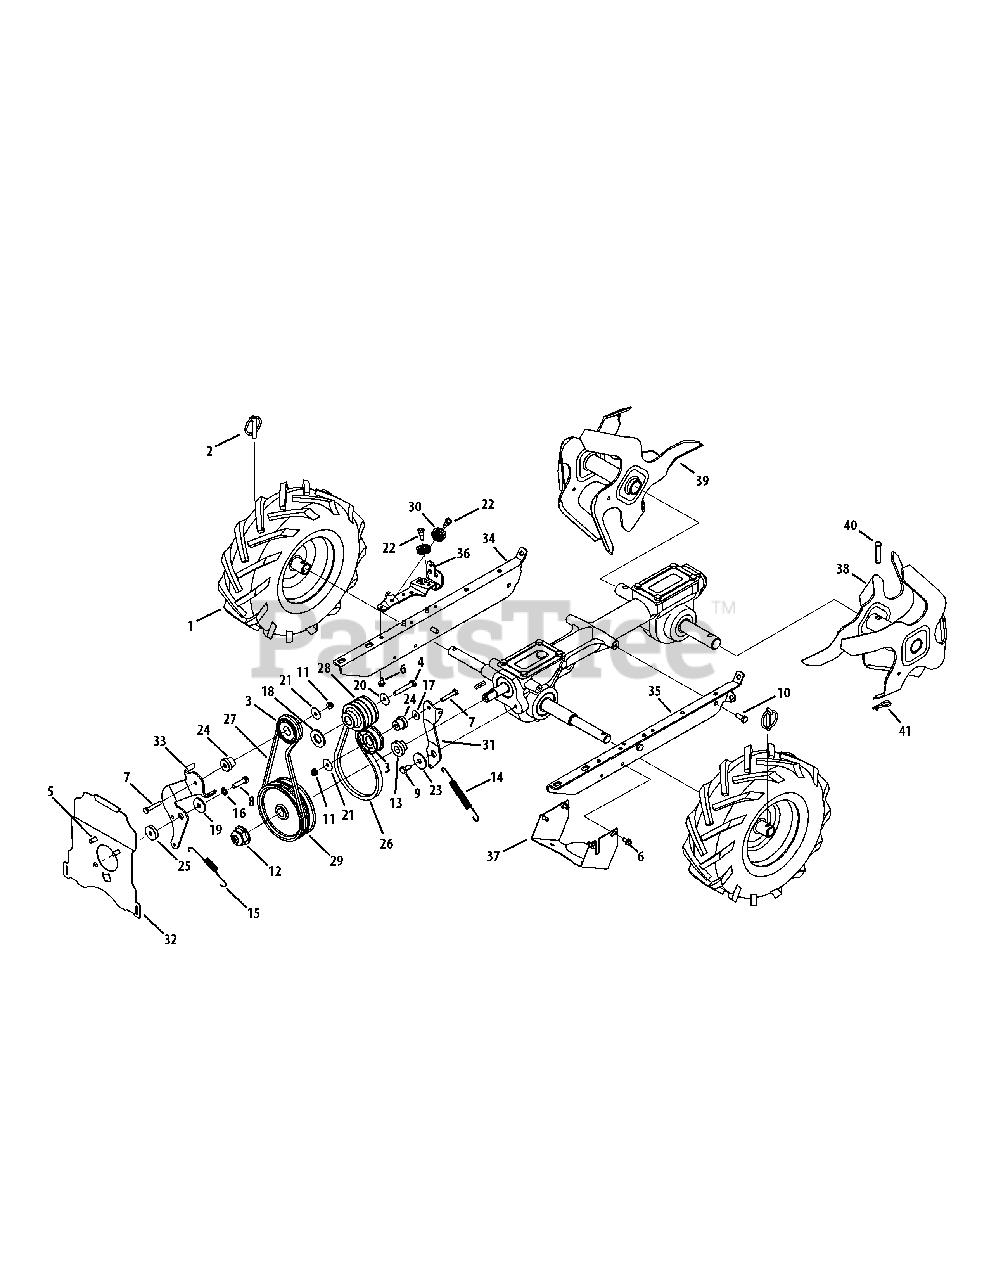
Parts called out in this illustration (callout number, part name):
1	Complete Whl. Ass., 13 x 5 x 6 (B, C)
2	Klik Pin
3	Idler Pulley Assembly
4	Hex Head Screw, 3/8-24 x 2.00
5	Hex Head Screw, 5/16-24 x .625
6	Self Tapping Screw, 1/4-20 x .500
7	Hex Head Screw, 1/4-20 x 1.50
8	Hex Head Screw, 5/16-18 x 1.25
9	Hex Head Screw, 5/16-18 x .75, Patch
10	Hex Head Screw, 5/16-18 x .75, STD
11	Nylon Hex Lock Nut, 1/4-20
12	Nut, 9/16-18, Flange Lock
13	Hub, 5/8 Spline
14	Spring, Extension:.480 OD X 5.00 LG
15	Spring, Extension
16	Lock Washer, 5/16
17	Washer, .28 x .74 x .063
18	Flat Washer, .760 X 1.50 X .120
19	Flat Washer, .330 X 1.25 X .120
20	Bell Washer, .396 x 1.140 x .095
21	Flat Washer, .265 x 1.0 x .030
22	Shoulder Screw, .340 x .335 1/4-28
23	Pivot Idler Spacer
24	Shoulder Spacer, .260 x .785 x .538
25	Pivot Idler Spacer
26	V-Belt, 4L x 25.375 Long
27	V-Belt, 3L x 29.125 Long
28	Engine Pulley
29	Transmission Pulley
30	Cable Roller
31	Idler Bracket, Forward
32	Cover Plate
33	Idler Bracket, Reverse
34	Mounting Frame, RH
35	Mounting Frame, LH
36	Pulley Bracket
37	Pulley Shield
38	Tine Assembly, LH
39	Tine Assembly, RH
40	Clevis Pin, .375 x 1.75
41	Internal Cotter Pin
